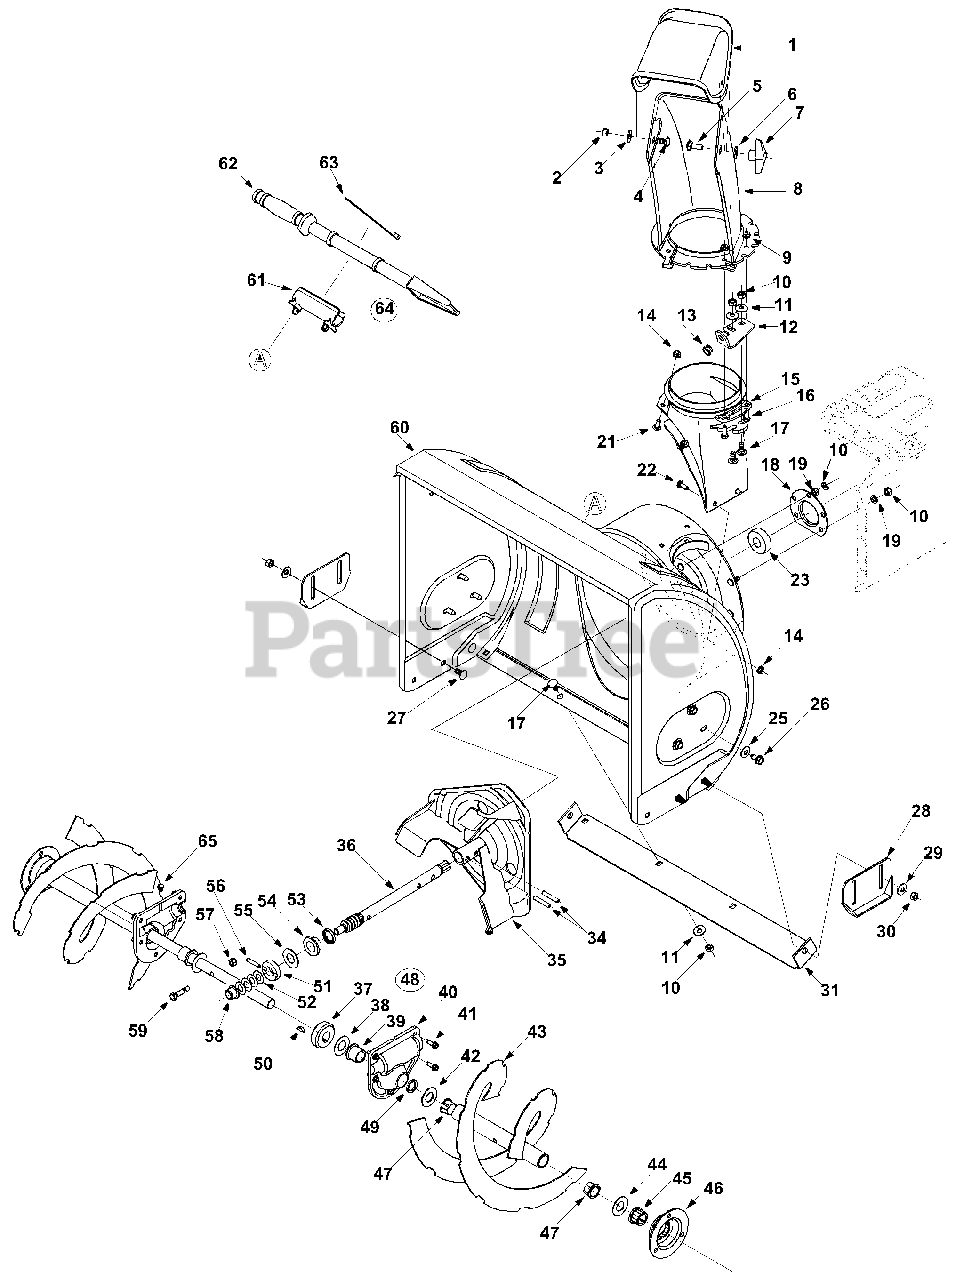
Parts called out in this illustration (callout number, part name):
1	Upper Chute
2	Hex Lock Nut 5/16-18
3	Washer
4	Carriage Bolt 5/16-18 x 0.75"
5	Carriage Bolt 5/16-18 x 1.0"
6	Washer
7	Hand Knob 5/16-18
8	Lower Chute
9	Flange Lock Nut 1/4-20
10	Hex Nut 5/16-18
11	Bell Washer
13	Plastic Bushing
14	Flange Lock Nut 1/4-20
15	Chute Flange Keeper
16	Chute Adapter
17	Carriage Bolt 5/16-18 x 0.75"
18	Bearing Housing
19	Lock Washer
21	Hex Bolt 1/4-20 x 0.75"
22	Carriage Screw 1/4-20 x 0.75"
23	Ball Bearing
25	Bell Washer
26	AB Screw 5/16-12 x 0.75"
27	Carriage Bolt 5/16-18 x 0.75"
29	Beleville Washer
30	Hex Nut 5/16-18
34	Spiral Pin
36	Worm Shaft
37	Flat Washer
38	Worm Gear
39	Spiral Axle
40	Gear Housing LH
41	Hex Bolt 1/4-20 x 0.75"
42	Flat Washer
45	Hex Flange Bearing
47	Flange Bushing
48	Gearbox Assembly
49	Oil Seal
50	Key
51	Thrust collar
52	Flat Washer
53	Oil Seal
54	Flange Bearing
55	Flat Washer
56	Spiral Pin
57	Hex Lock Nut 5/16-18
58	Flange Bearing
59	Shear Bolt 5/16-18 x 1.5"
62	Chute Clean-out Tool
63	Cable Tie
64	Chute Clean-Out Tool Assy. Comp.
